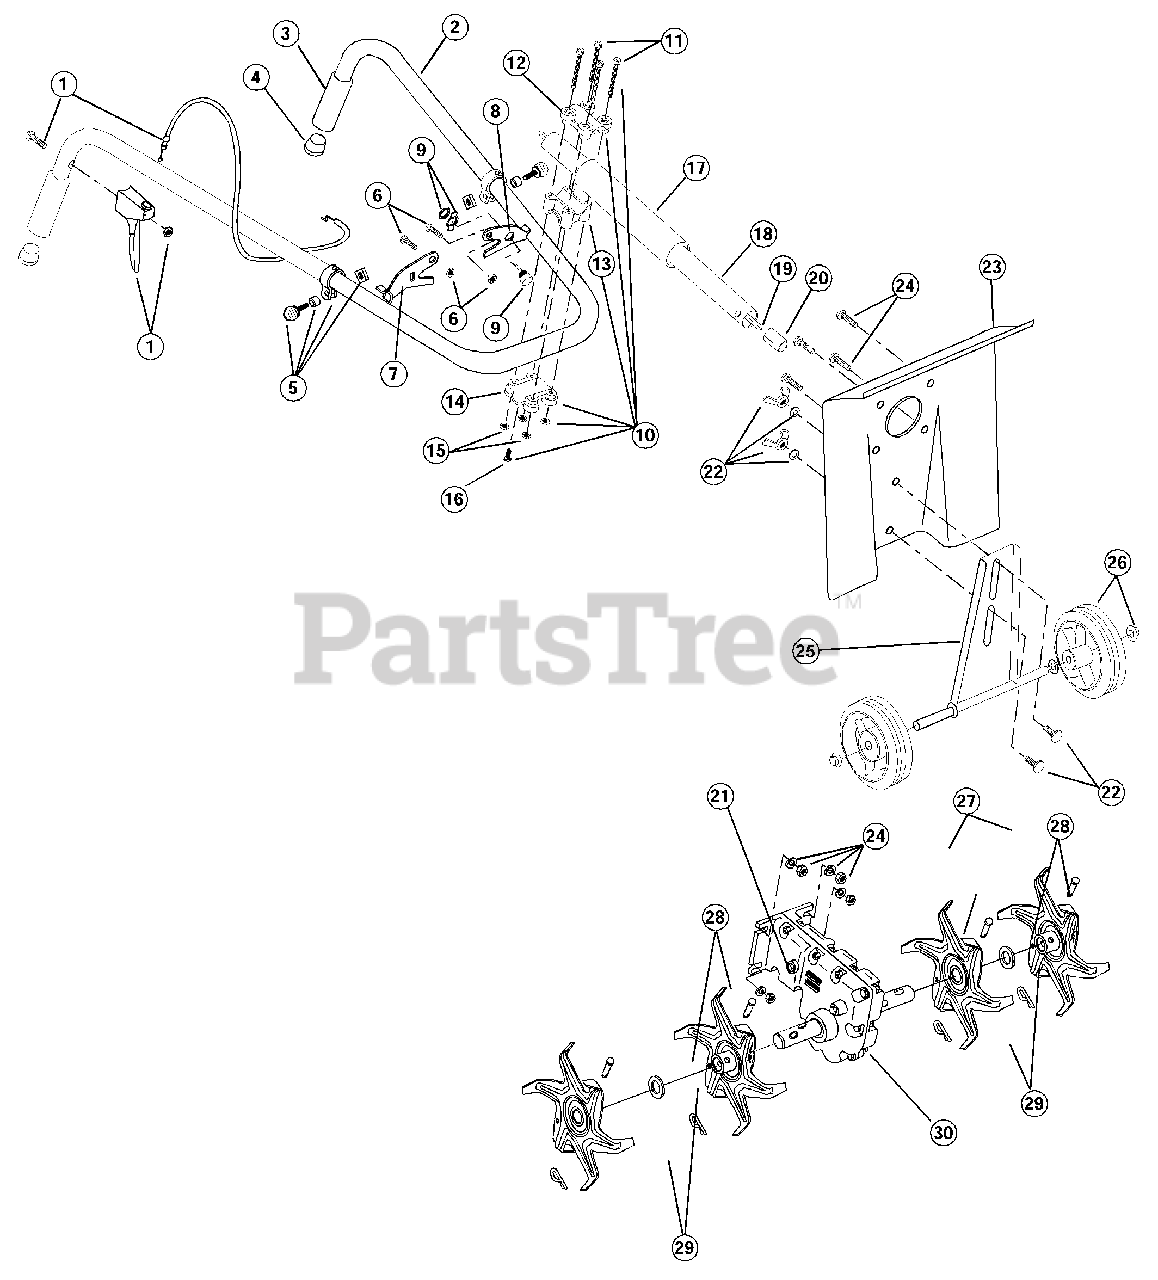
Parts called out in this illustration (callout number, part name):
1	Throttle Trigger and Cable Assembly
2	Handle Bar w/Clamp Assemblies
4	Tube Closure
5	Clamp Assembly
6	Engine Bracket Mounting Hardware
7	Engine Mount Bracket, R.H.
8	Engine Mount Bracket, L.H.
9	Switch Assembly
10	Handle Bracket Assembly
12	Upper Handle Clamp
13	Middle Handle Clamp
14	Lower Handle Clamp
16	Anti-Rotation Screw
18	Drive Shaft Housing Assembly
19	Flexible Drive Shaft
20	Retainer Sleeve
21	Sleeve Retainer Bolt
22	Wheel Bracket Mounting Hardware
24	Guard Mounting Hardware
25	Wheel Bracket Assembly
26	Wheel Assembly
27	Tine Fastener Assembly
28	Tine Assembly (Left Outer or Right Inner)
29	Tine Assembly (Left Inner or Right Outer)
30	Gear Box Assembly
